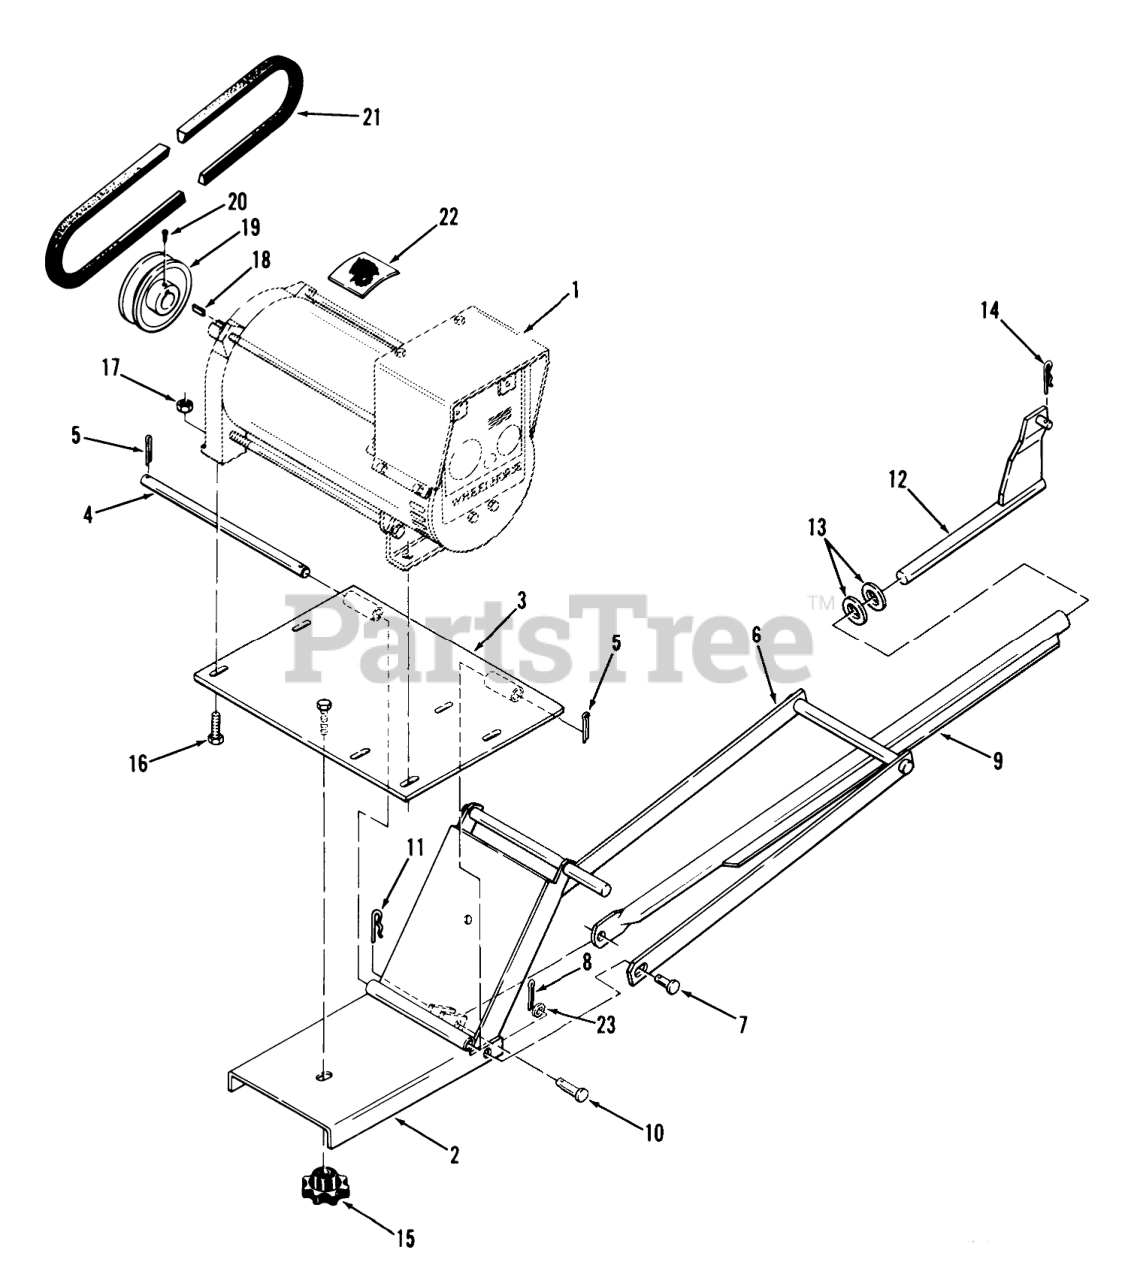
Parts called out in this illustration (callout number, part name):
1	Alternator 3000 Watt (Generac No. 6509-0)
1	Alternator 5000 Watt (Generac No. 6511-1)
2	Front Hitch
3	Mounting Plate
4	Pivot Rod
5	Cotter Pin
6	Mid Hitch
8	Cotter Pin
9	Lift Tube
10	Clevis Pin 5/16 x 1 1/4
11	Hairpin Cotter
12	Lift Rod
13	Washer
14	Hairpin
15	Knob
16	Bolt
17	Nut
18	KEY-STRAIGHT
19	Pulley
21	Drive Belt
22	DECAL-LOGO
23	Washer
